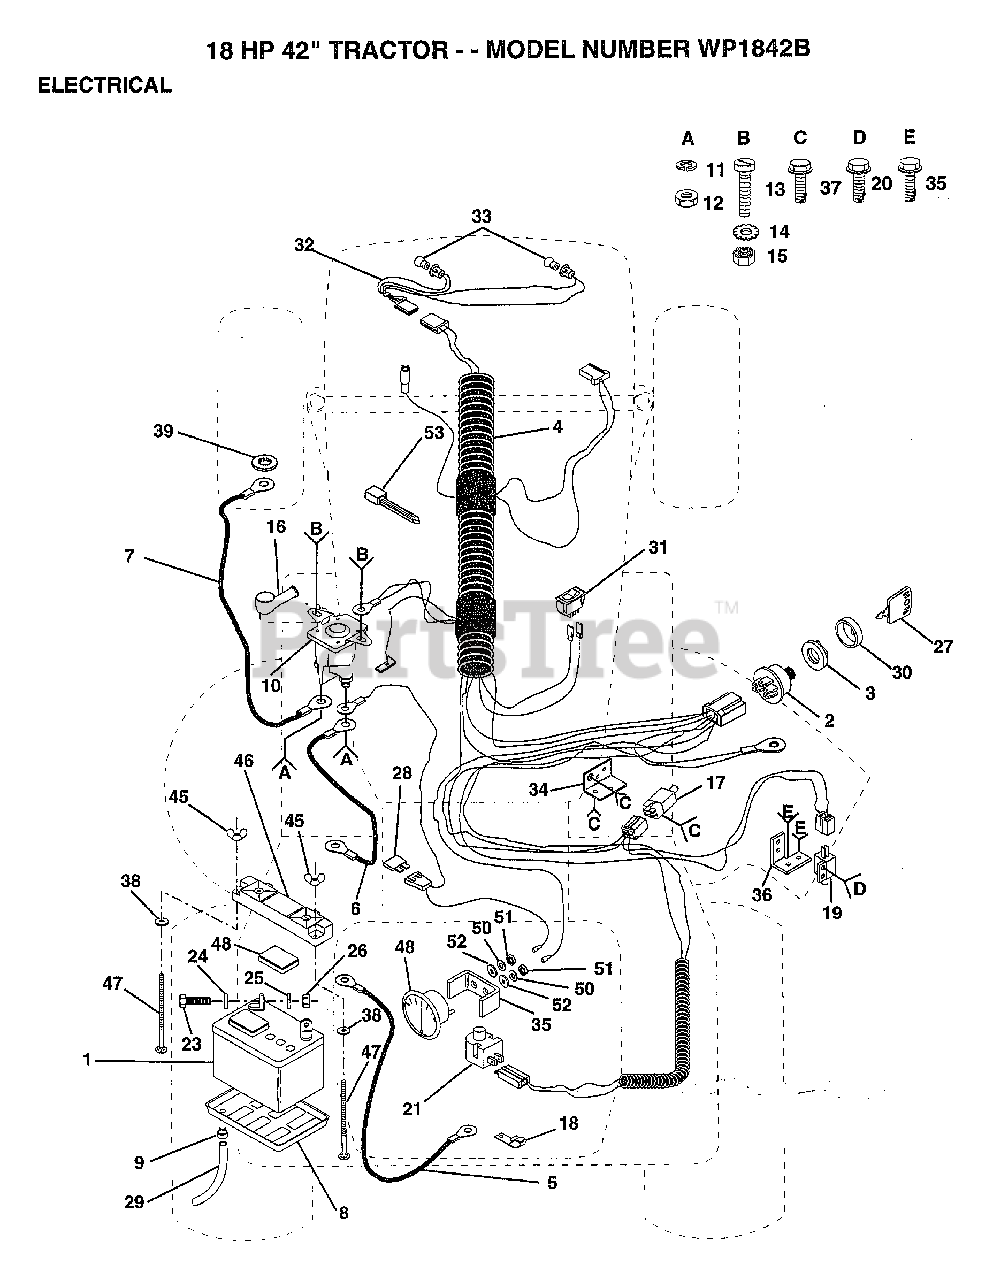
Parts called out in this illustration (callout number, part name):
3	NUT IGNITION
4	HARNESS.IGN.B&S
5	CABLE T
6	CABLE-BATTERY T
7	"CABLE T, BATTERY"
8	"TRAY T, BATTERY"
9	HOSE CLAMP T
12	NUT
13	BOLT
15	NUT
17	SWITCH INTERLOCKT
18	CLIP T
19	SWITCH-INTER. GT
20	SCREW
21	SWITCH SEAT
22	"CAP,BATTERY "
23	BOLT LT
24	WASHER
25	LOCKWASHER
27	KEY
28	FUSE HYT
29	"DRAIN TU T, BATT"
31	SWITCH LT
34	BRACKET LT
35	SCREW
36	SWITCH BRACKET
37	SCREW
38	WASHER.3/4X1X18GA
39	LOCKWASHER
47	BOLT
48	AMMETER T
52	WASHER
53	WIRE TIE
